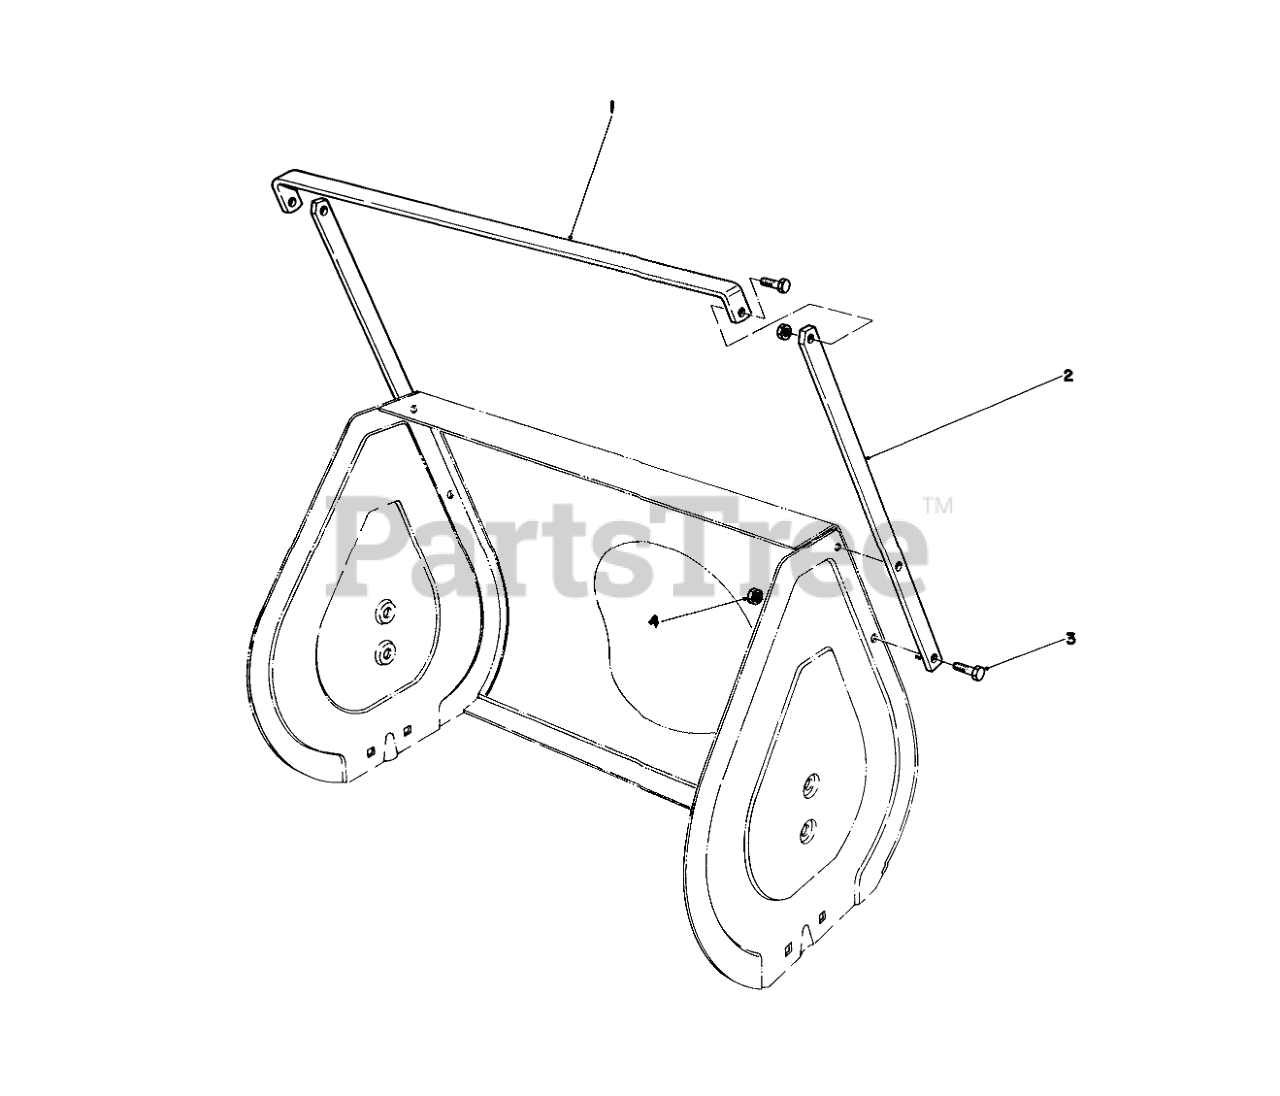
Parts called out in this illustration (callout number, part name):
1	Drift Breaker-Top
2	Drift Breaker-Side
3	SCREW-HH
4	NUT-LOCK, NI
